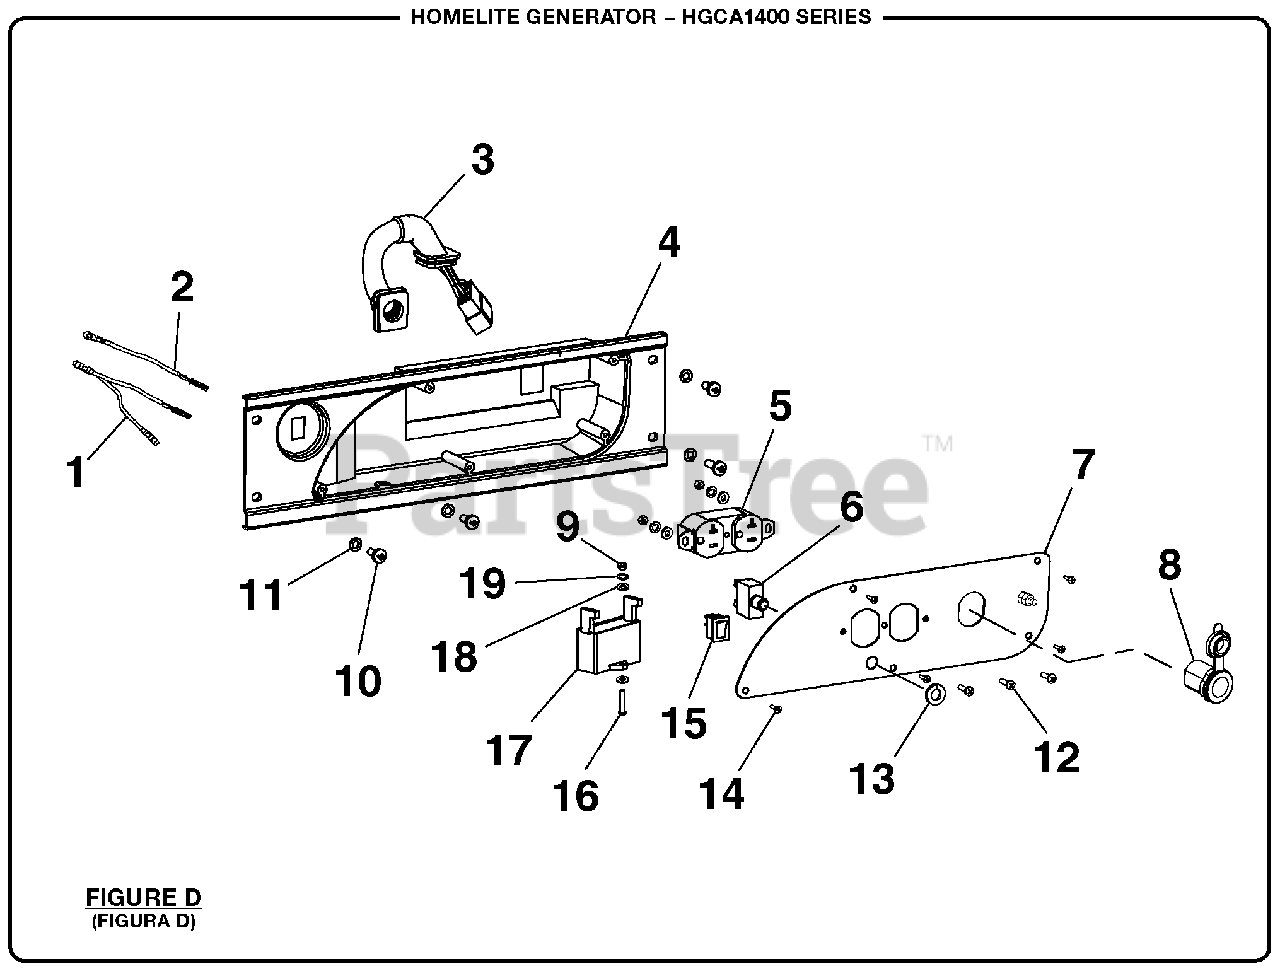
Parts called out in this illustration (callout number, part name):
1	Wire (Double End)
2	Wire (Single End)
3	Wire Harness
4	Control Panel Box
6	Circuit Breaker (12 AMP)
7	Cover Plate
9	Hex Nut (M4)
10	Screw (M6 x 12 mm)
11	Washer (M6)
12	Screw (M4 x 12 mm)
13	Knurled nut
14	Screw (M4 x 15 mm)
16	Bolt (M4 x 15 mm)
18	Washer (M4)
19	Wavy Washer
